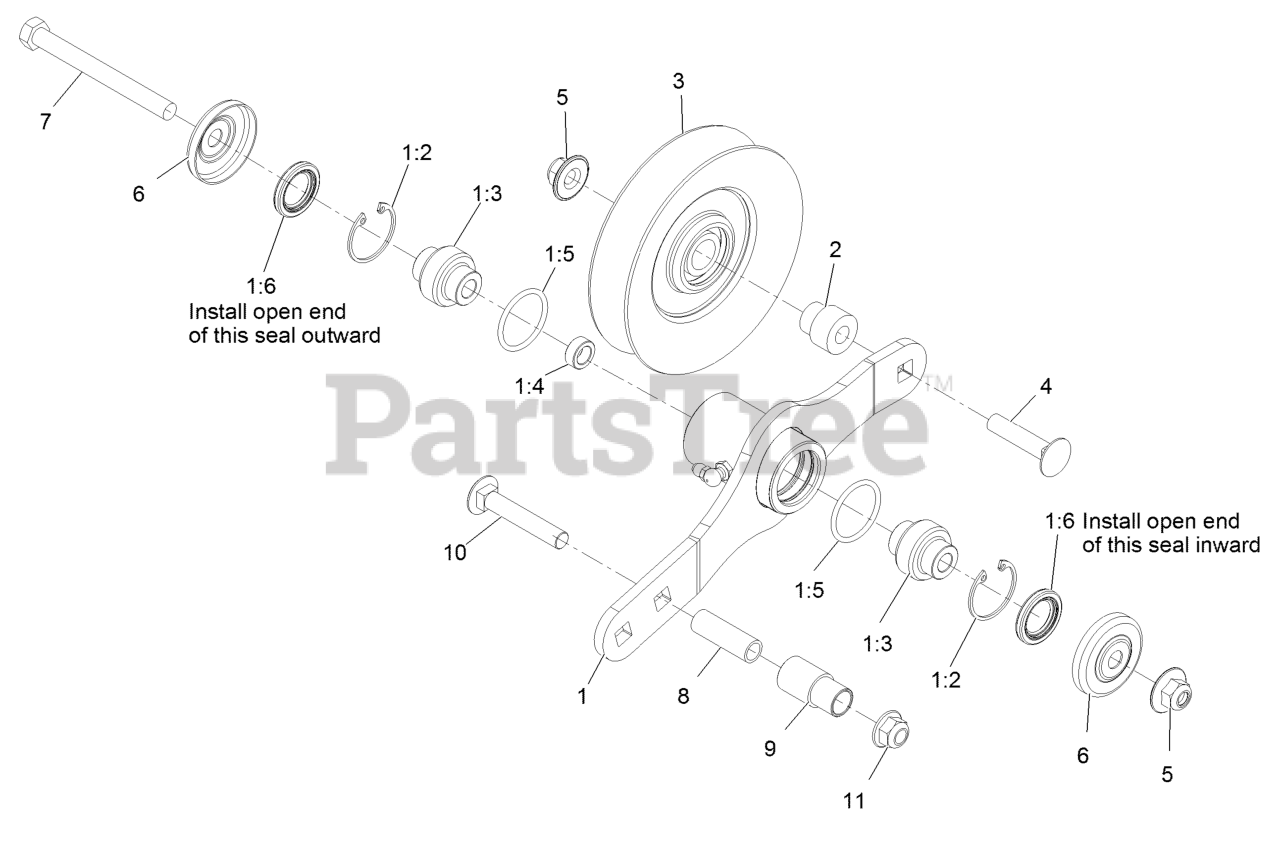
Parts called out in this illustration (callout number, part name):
1	ASM-Ttnr Arm W/Bearing
1:2	RING-SNAP
1:3	BEARING-SPHERICAL
1:6	SEAL-LIP, SINGLE
2	BUSHING-IDLER
3	PULLEY-IDLER
4	SCREW-CARR
5	Nut-Nyloc 3/8-16 Flg
6	GUARD-TOP
7	SCREW-HH
9	BUSHING,PLASTIC
10	Bolt-Carriage 3/8-16 X 2 1/4
11	NUT-HF, NI
